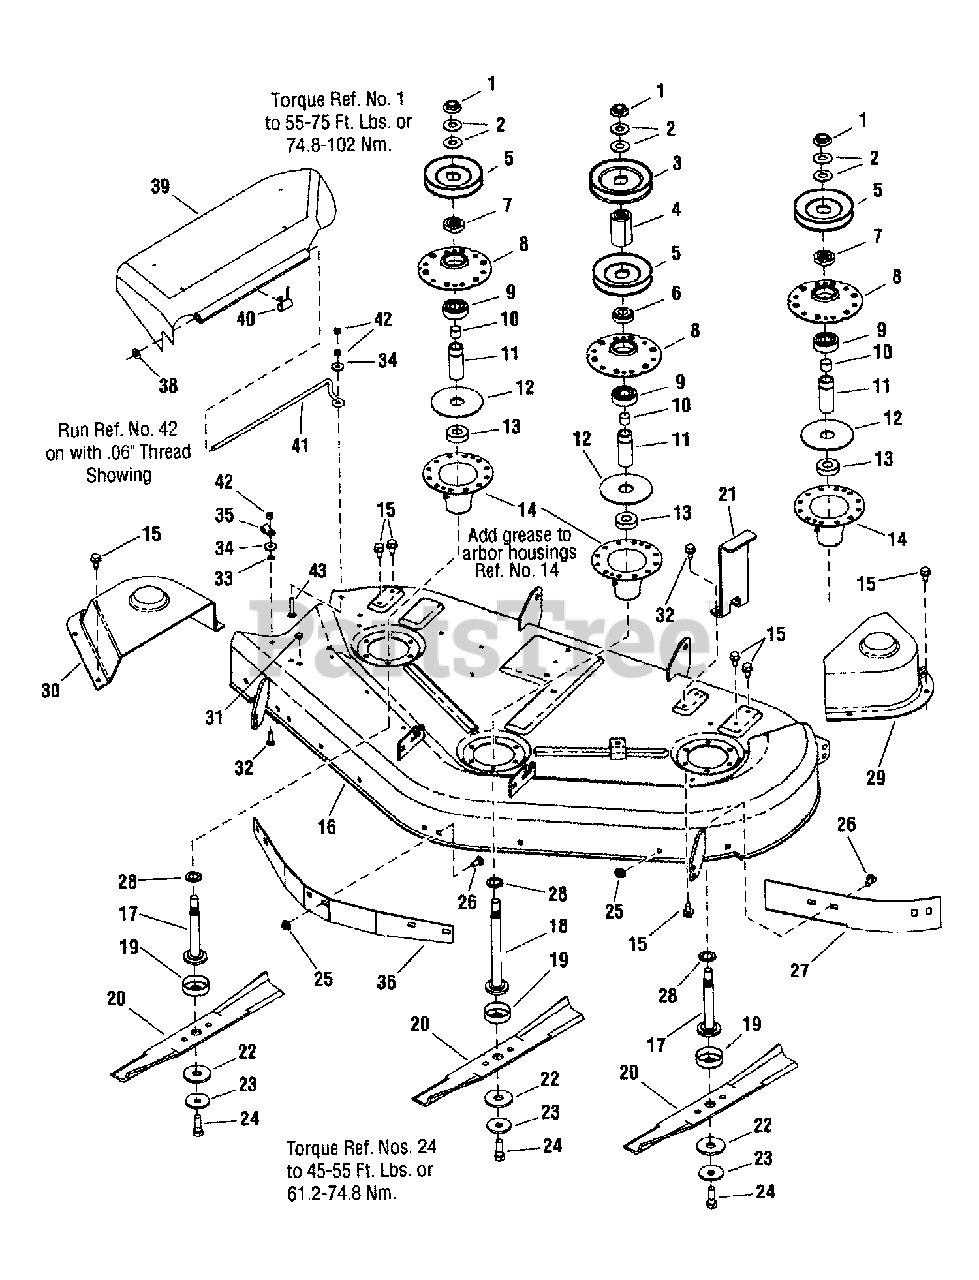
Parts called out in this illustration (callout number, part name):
1	NUT, 9/16-18 Hex Flange (non-locking)
2	WASHER, Belleville
3	PULLEY, Deep Groove, 4.6
4	HUB, Double Pulley
6	HUB, Double Pulley
7	HUB, Pulley, Center & R.H.
8	HOUSING, Arbor Top
9	BEARING, Spindle
10	SPACER, Bearing Sleeve
11	SPACER, Powdered Metal
12	GASKET, Foam Poly
13	BALL BEARING, 11/16 x 1-9/16 x 15/32 Long
14	HOUSING, Arbor Bottom w/Lube Fitting
15	SCREW, 5/16-18 x 5/8" Hex Washer Self-Tap
16	WELDMENT, 50" Mower Housing (orange)
17	SHAFT, Arbor Short
18	SHAFT, Arbor Long
19	SHIELD, Grass Lower Arbor Heat Treated
20	BLADE, Mower, 50" Deck
22	WASHER, 11/16 x 2" Hex
23	WASHER, Spring
24	SCREW, 7/16-14 x 1-1/4" Hex Head Cap, GR8
25	NUT, 5/16-18 Hex Flange Lock Large Black
26	BOLT, 5/16-18 x 3/4" Round Head Short Square Neck, GR5
27	BAFFLE, Anti-Blowout
28	WASHER, Cup
29	COVER, Arbor
30	COVER, Arbor
31	PLUG, Hole (for.344 Square Hole)
32	BOLT, 1/4-20 x 7/8" Round Head Square Neck, GR5
33	RETAINER, 1/4" Bolt
34	WASHER, Large (1/4 I.D. x 5/8 O.D. x .134/.109 Thick)
36	BAFFLE, Front 44 & 50" Decks
38	WASHER, 5/16"
39	DEFLECTOR, Discharge
40	SPRING, Torsion Chute 44" & 50" Decks
41	ROD, Deflector, Front
42	NUT, 1/4" Hex Lock Esna Light
43	BOLT, 1/4-20 x 1-1/2" Round Head Square Neck, GR5
